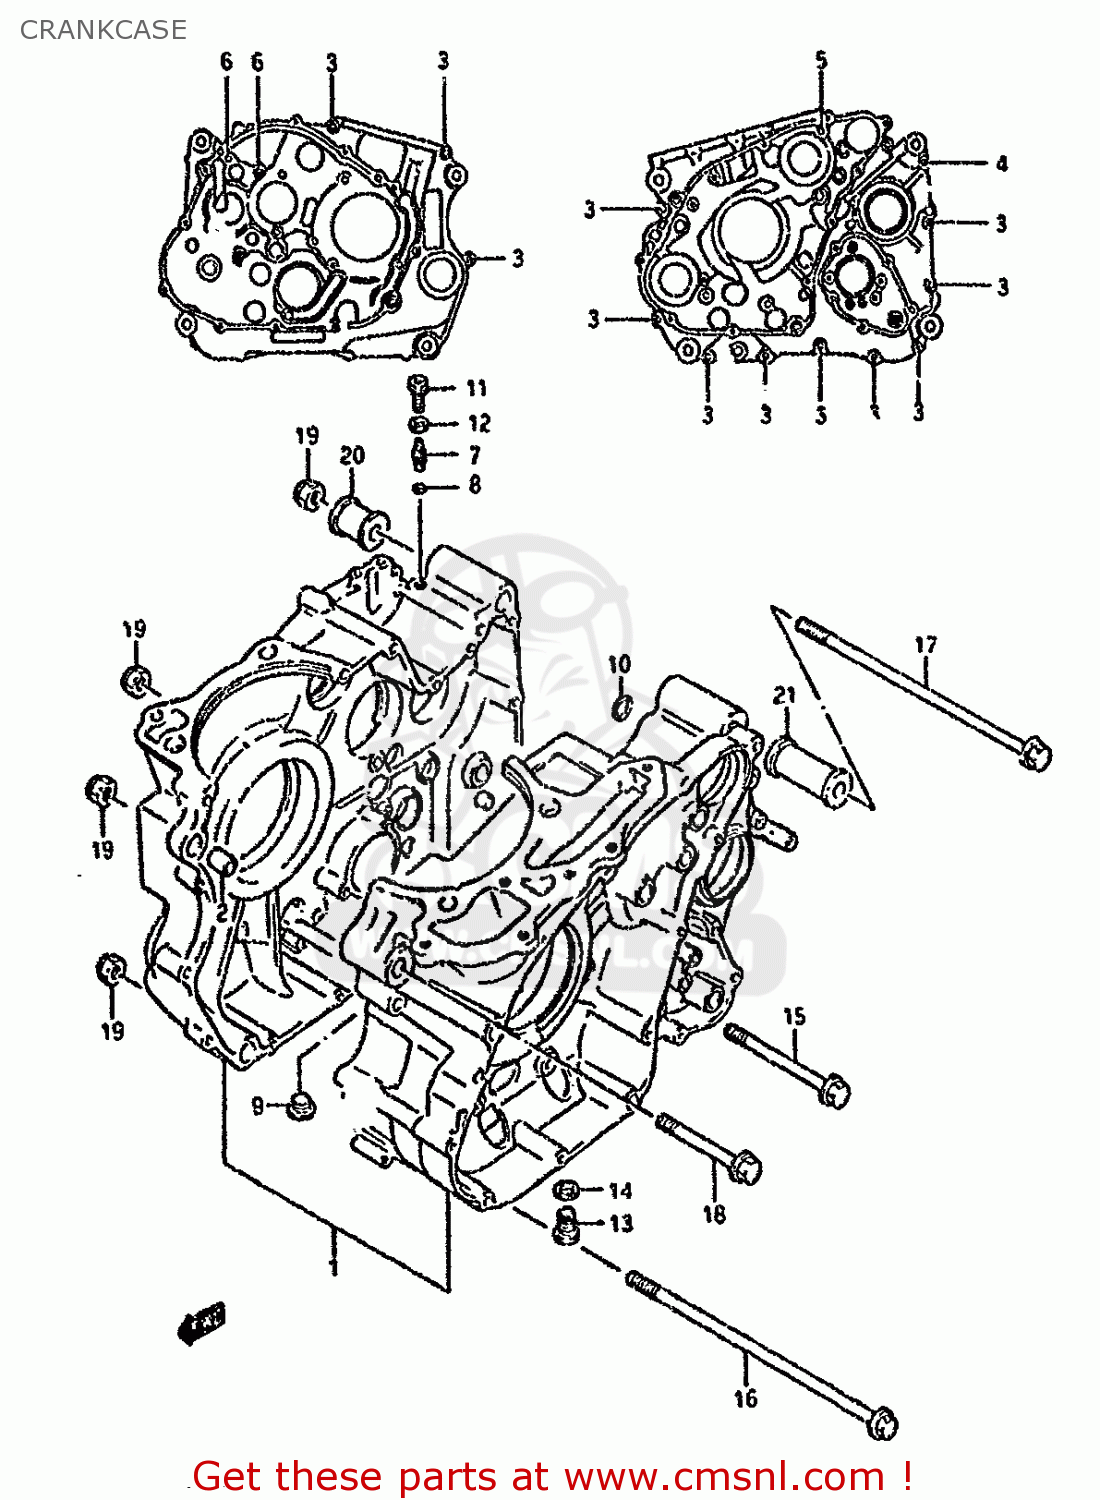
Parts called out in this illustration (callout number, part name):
1	CRANKCASE SET
2	PIN
3	BOLT
4	BOLT
5	BOLT
6	BOLT
7	JET(12)
8	O RING(D:1.2,ID:4)
9	PLUG
10	O RING(D:1.9,ID:11)
11	BOLT
12	GASKET 8.2X14X1 (NAS)
13	BOLT
14	GASKET(12.1X16.2X3.7) (NAS)
15	BOLT(10X130)
16	BOLT (10X215)
17	BOLT 10X230
18	BOLT 10X70
19	NUT
20	SPACER,ENGINE MOUNT
21	SPACER,ENG MTG,R(L:60)
